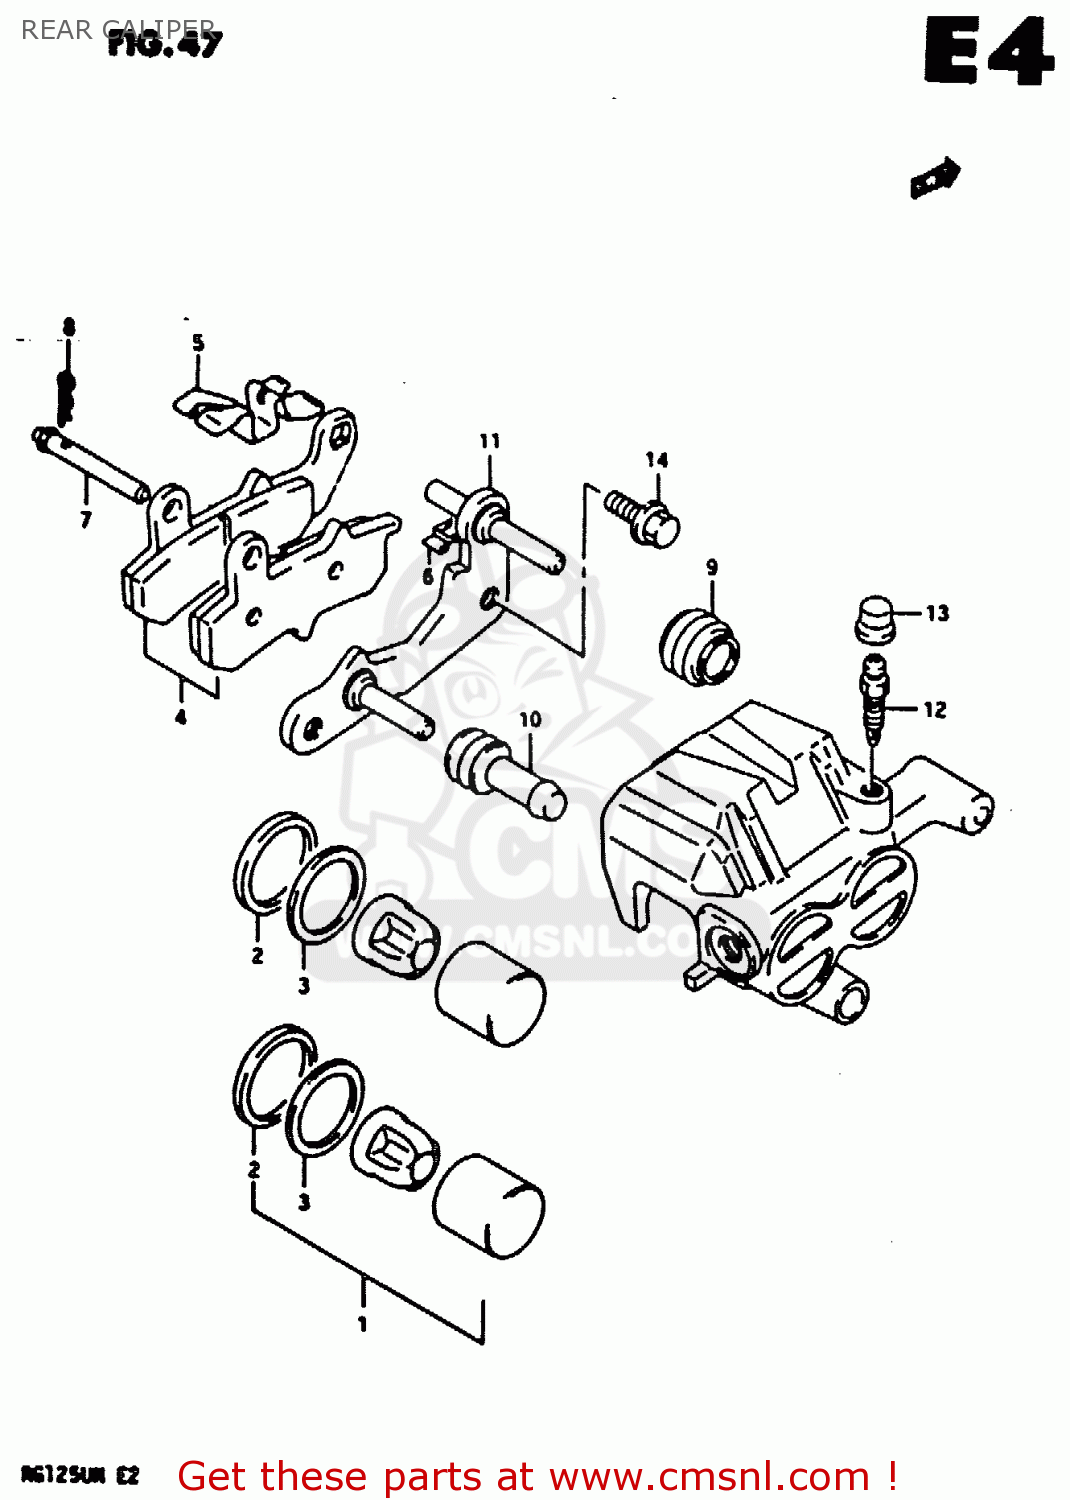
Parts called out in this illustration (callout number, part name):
1	BRAKE PISTON SET
2	SEAL,PISTON
3	SEAL,WIPER
4	PAD SET (NAS)
5	SPRING,PAD
6	GUIDE,PAD
7	PIN,PAD
8	CLIP,PAD PIN
9	BOOT,AXLE
10	INSULATOR,AXLE
11	CARRIER
12	BLEEDER
13	CAP,BREATHER
14	BOLT
